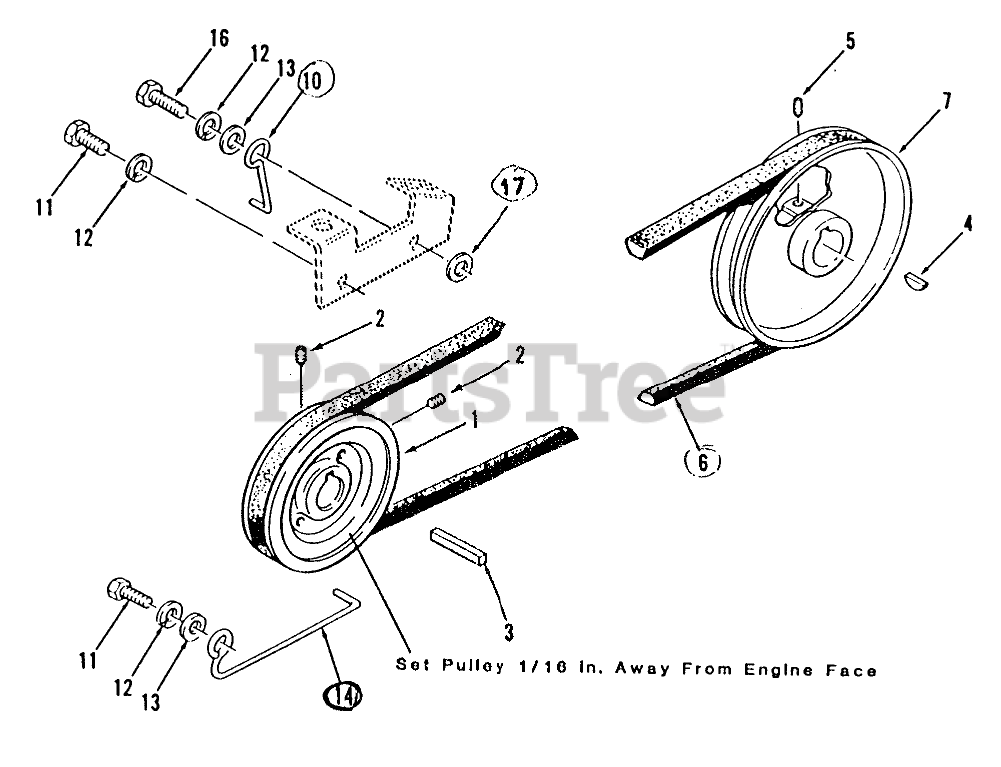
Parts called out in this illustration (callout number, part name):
1	PULLEY
2	Set Screw
4	KEY-HI PRO
5	Set Screw
6	V-BELT TRANS DRIVE
7	PULLEY-TRANSMISSION
10	GUIDE BELT TOP
11	7/16-14 x 1 1/4 Bolt
12	LOCKWASHER
13	WASHER
14	Belt Guide-Bottom 308-8 Only
17	SPACER-SHORT TIGHT
